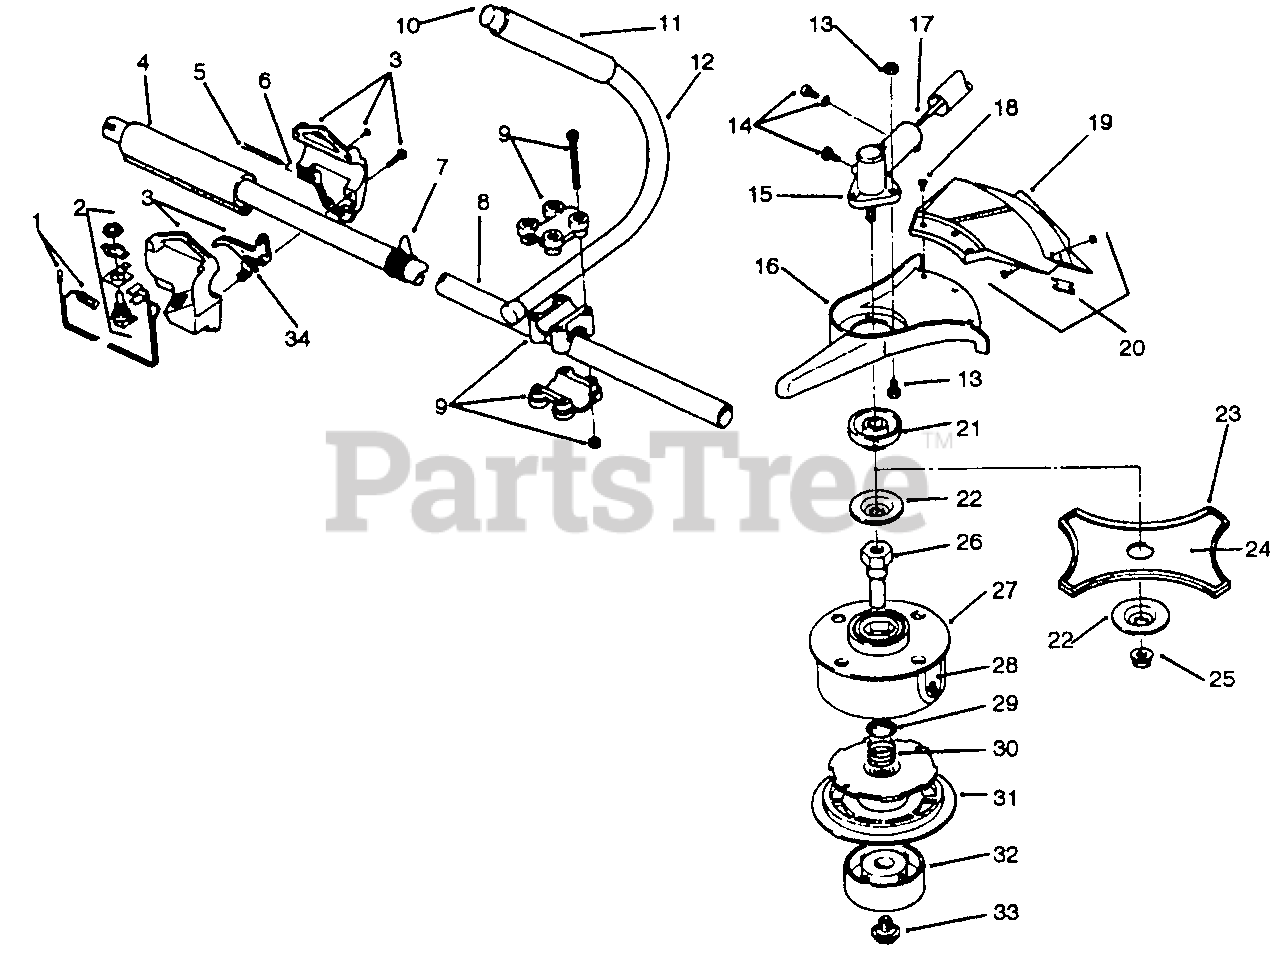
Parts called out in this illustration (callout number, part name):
1	Assembly-Wire Lead
2	Assembly-Switch
3	Assembly-Throttle Trigger
4	Grip-Handle, Main
5	Assy.-Throttle Cable
6	Cable-Throttle
7	Clamp-Shoulder Strap
8	Assy.-Drive Shaft
9	Assy.-Handle Bracket (Incl. 4 Screws 7 4 Nuts)
10	Closure-Tube
12	Assy.-J-Handle (Incl. Ref. No. 10 & 11)
13	Screws-Guard Mount
14	Screws & Grease Plug
15	Assembly-Gear Box
16	Mount-Guard
17	Shaft-Flexible Drive
18	Screws-Guard Mounting
19	Assy.-Guard & Blade (Incl. Ref. No. 20)
20	Assembly-Blade (Incl. 2 Screws & 2 Nuts)
21	Driver-Blade
22	Washer-Lower Retaining
23	Cover-Blade
24	Blade (Incl. Ref. No. 23)
25	Nut-Lock
26	Shaft-Spool
27	Assy.-Outer Spool & Eyelet
29	Retainer (10 Pack)
31	Reel-Inner
32	Assy.-Bump Head
33	Assy.-Bump Head Knob
34	Spring-Throttle Trigger
